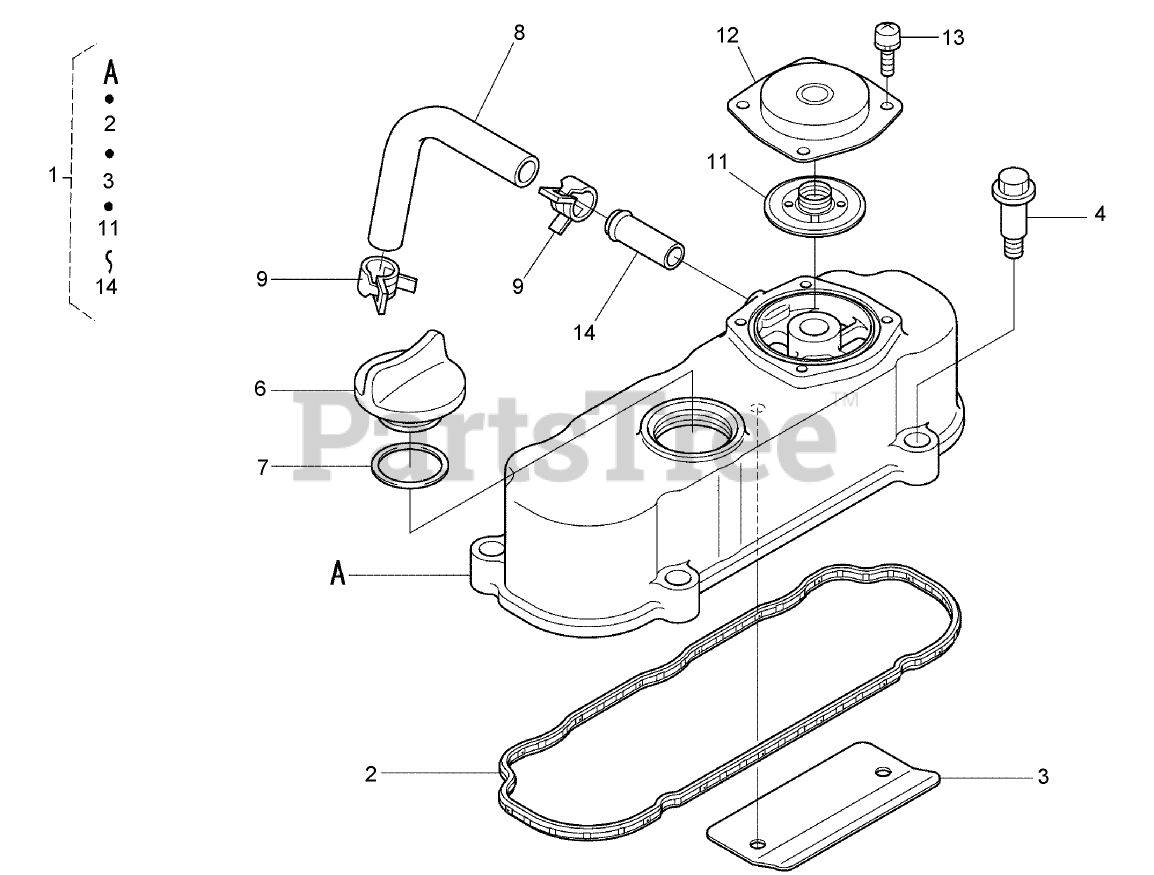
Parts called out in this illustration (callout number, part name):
1	CYLINDER HEAD COVER ASM
2	GASKET-COVER, HEAD
3	SHIELD-BREATHER
6	PLUG-FILLER, OIL
7	O-RING
8	TUBE-BREATHER
9	CLAMP-HOSE
11	VALVE-BREATHER
12	COVER-BREATHER
13	SCREW (WITH WASHER)
14	PIPE-RETURN, WATER
